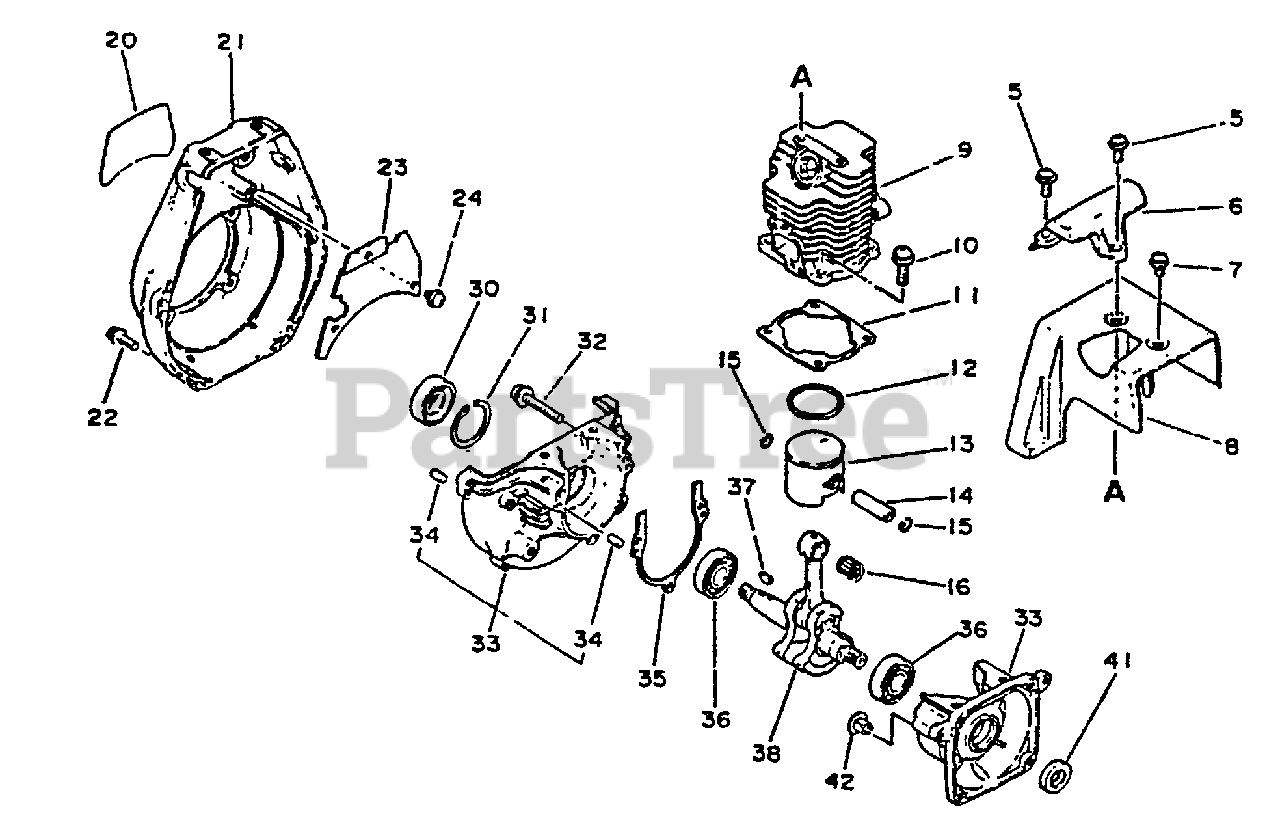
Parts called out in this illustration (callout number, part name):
5	SCREW - 4X14
6	GUARD - TOP
7	SCREW - 4X10
8	COVER, ENGINE
9	CYLINDER
10	SCREW - 5X16
11	GASKET, CYLINDER
12	RING, PISTON
13	PISTON
14	PIN, PISTON
15	RING, RETAINING
16	BEARING, NEEDLE
20	LABEL - MODEL
21	COVER, FAN
22	SCREW - 4X16
23	SHIELD, FAN
24	SCREW - 4X8
30	SEAL, OIL - 12
31	RING, RETAINING - 28
32	SCREW - 5X28
33	CRANKCASE KIT
34	PIN - LOCATING
35	GASKET, CRANKCASE
36	BEARING, BALL - 6001C3
38	CRANKSHAFT ASSY
41	SEAL, OIL
